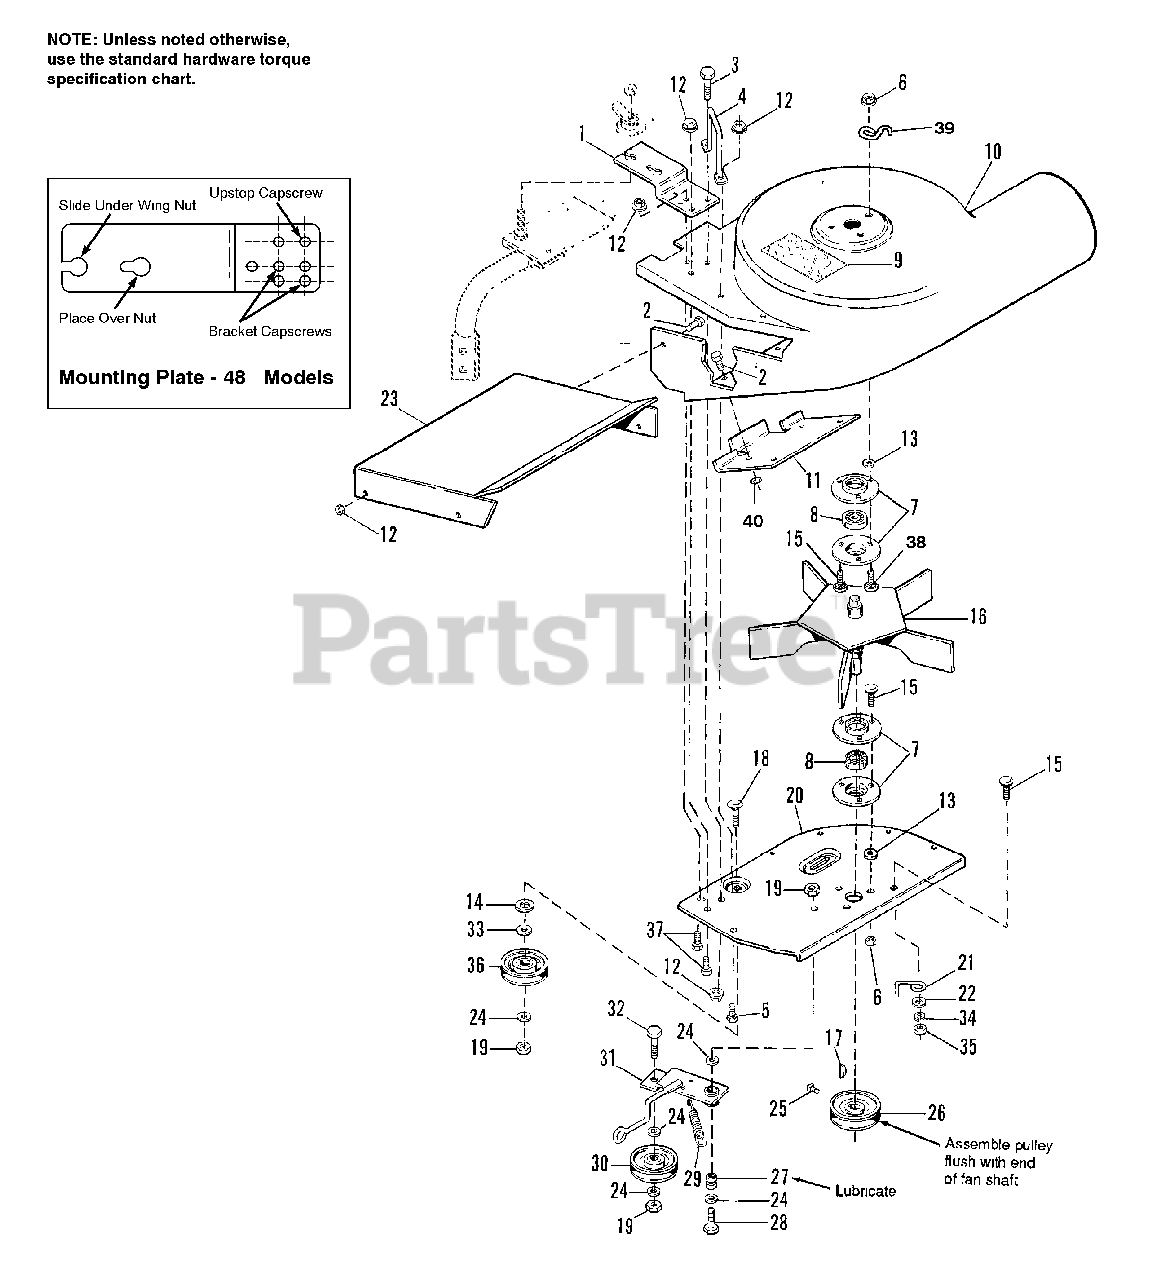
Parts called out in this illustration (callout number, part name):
1	PLATE, Mounting
2	CAPSCREW, Hex Hd,1/4-20 x 5/8
3	CAPSCREW, Hex Hd,1/4-20 x 2-1/4
4	STOP, Deflector
5	CAPSCREW, Hex Hd, 1/4-20 x 7/8
6	NUT, Hex Flange Whiz Lock, 5/16-18
7	RETAINER, Bearing
9	DECAL, Danger
10	HOUSING, Blower
11	HOOK, Stone Guard
12	NUT, Hex Flange Whiz Lock, 1/4-20
13	NUT, Push, 5/16
14	WASHER, Plain,1/2
15	CARRIAGE BOLT, 5/16-18 x 3/4
16	FAN ASSEMBLY (5 Blade)
17	KEY, Woodruff, 3/16
18	CARRIAGE BOLT, 3/8-16 x 1-1/4
19	NUT, Hex Jam Lock, 3/8-16
20	PLATE, Shroud
22	WASHER, 5/16
23	COVER, Top
24	WASHER, 3/8
25	SETSCREW, Sqr Hd, 5/16-18 x 3/8
26	PULLEY, Driven
27	SPACER
28	CAPSCREW, Hex Hd, 3/8-16 x 1-1/2
29	SPRING, Extension
30	PULLEY, Idler, Adjustable
31	IDLER ARM ASSEMBLY
32	CAPSCREW, Hex Hd, 3/8-16 x 1
33	WASHER, 3/8
34	WASHER, Lock, 5/16
35	NUT, Hex, 5/16-18
36	PULLEY, Idler, Fixed
37	CAPSCREW, Hex Hd, 1/4-20 x 3/4
38	CARRIAGE BOLT, 5/16-18 x 7/8
40	NUT, Hex Nylon Lock, 1/4-20
